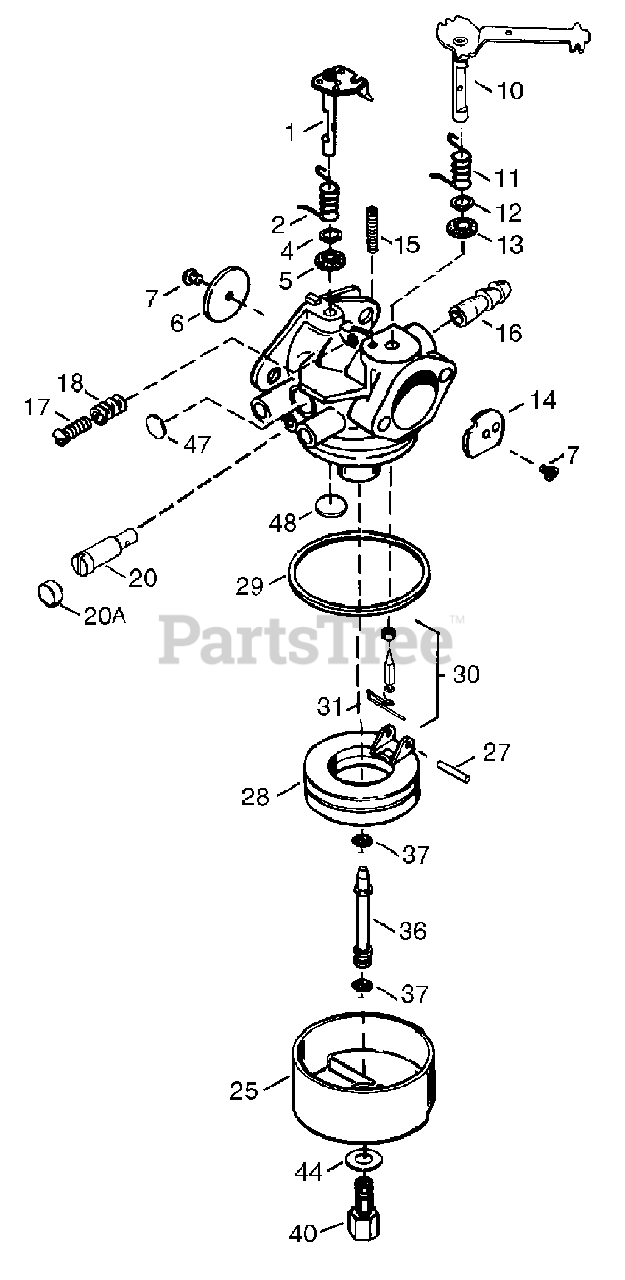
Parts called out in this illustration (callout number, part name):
1	Throttle Shaft & Lever Assembly
2	Throttle Return Spring
4	Dust Seal Washer
5	Dust Seal (Throttle)
6	Throttle Shutter
7	Shutter Screw
10	Choke Shaft & Lever Assembly
11	Choke Return Spring
12	Dust Seal Washer
13	Dust Seal (Choke)
14	Choke Shutter
15	Choke Positioning Spring
16	Fuel Fitting
17	Throttle Crack Screw/Idle Speed Screw
18	Tension Spring
20	Idle Mixture Screw
20A	Idle Restrictor Screw
25	Float Bowl
27	Float Shaft
28	Float
29	Float Bowl "O"-Ring
30	Inlet Needle, Seat & Clip
31	Spring Clip
36	Main Nozzle Tube
37	O Ring, Main Nozzle Tube
40	High Speed Bowl Nut
44	Bowl Nut Washer
47	Welch Plug, Idle Mixture Well
48	Welch Plug, Atmospheric Vent
